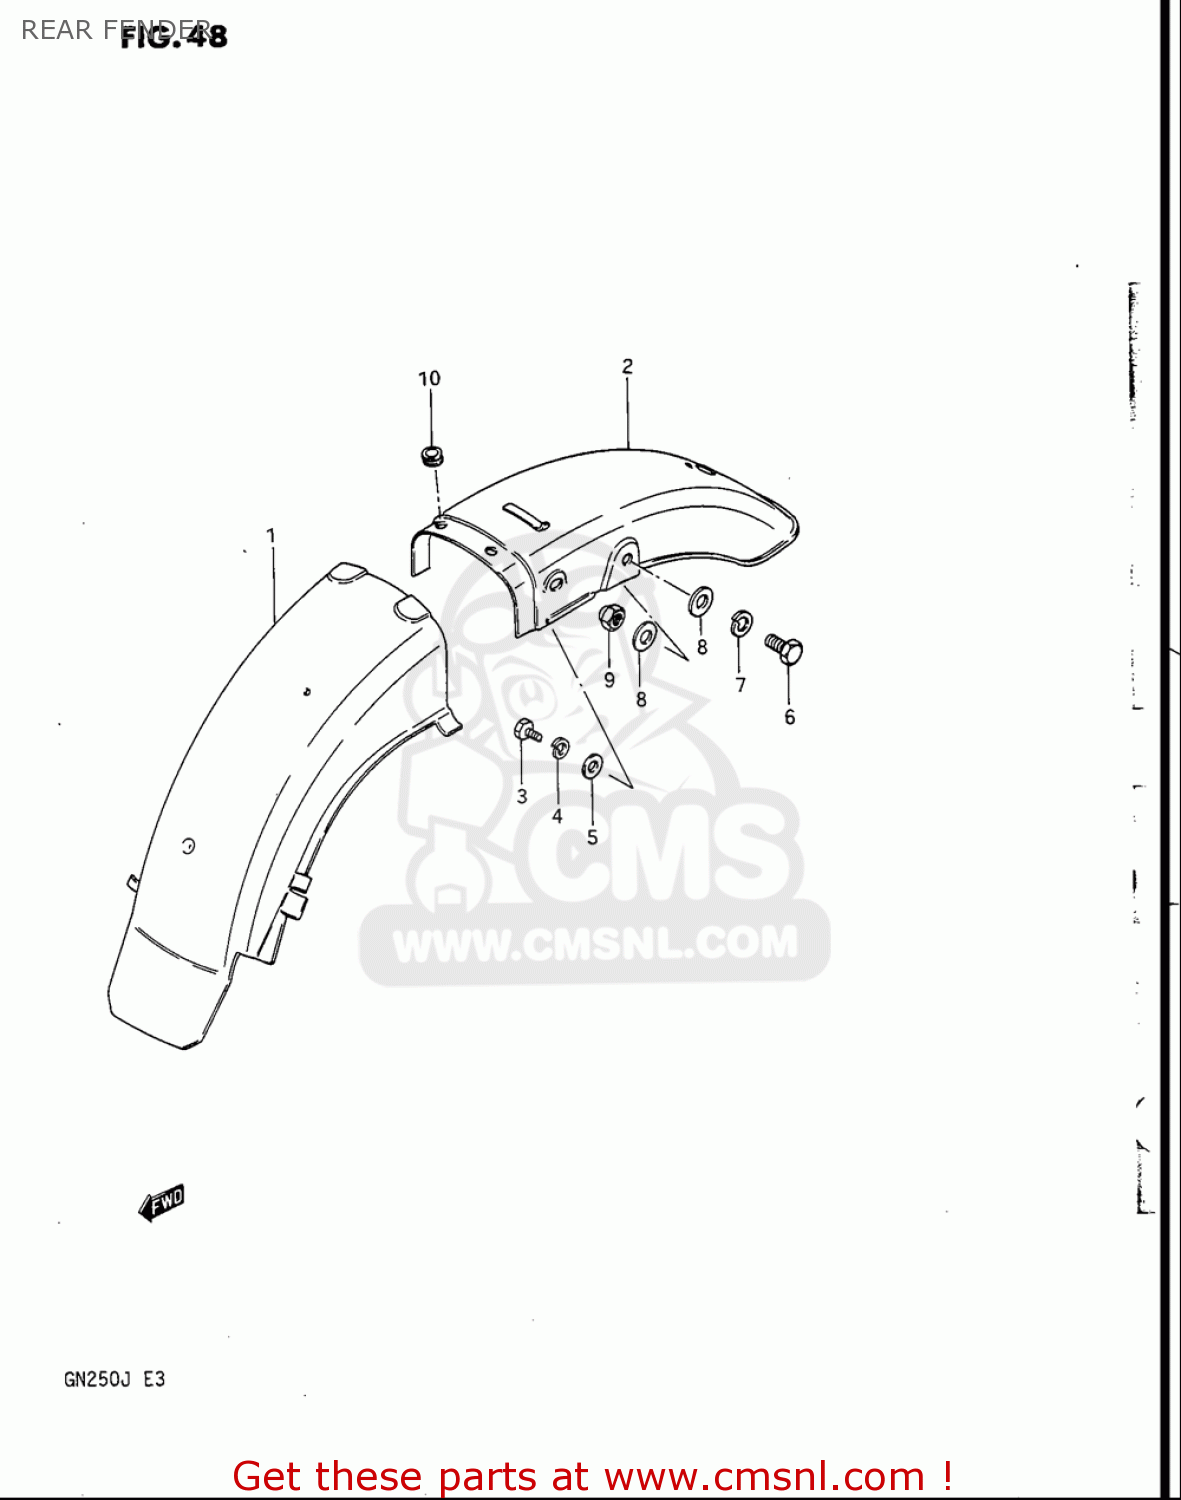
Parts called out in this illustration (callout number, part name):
1	BODY,FR
2	FENDER,RR
3	BOLT
4	WASHER,LOCK
5	WASHER
6	BOLT
7	WASHER,LOCK
8	WASHER
9	NUT
10	CUSHION
